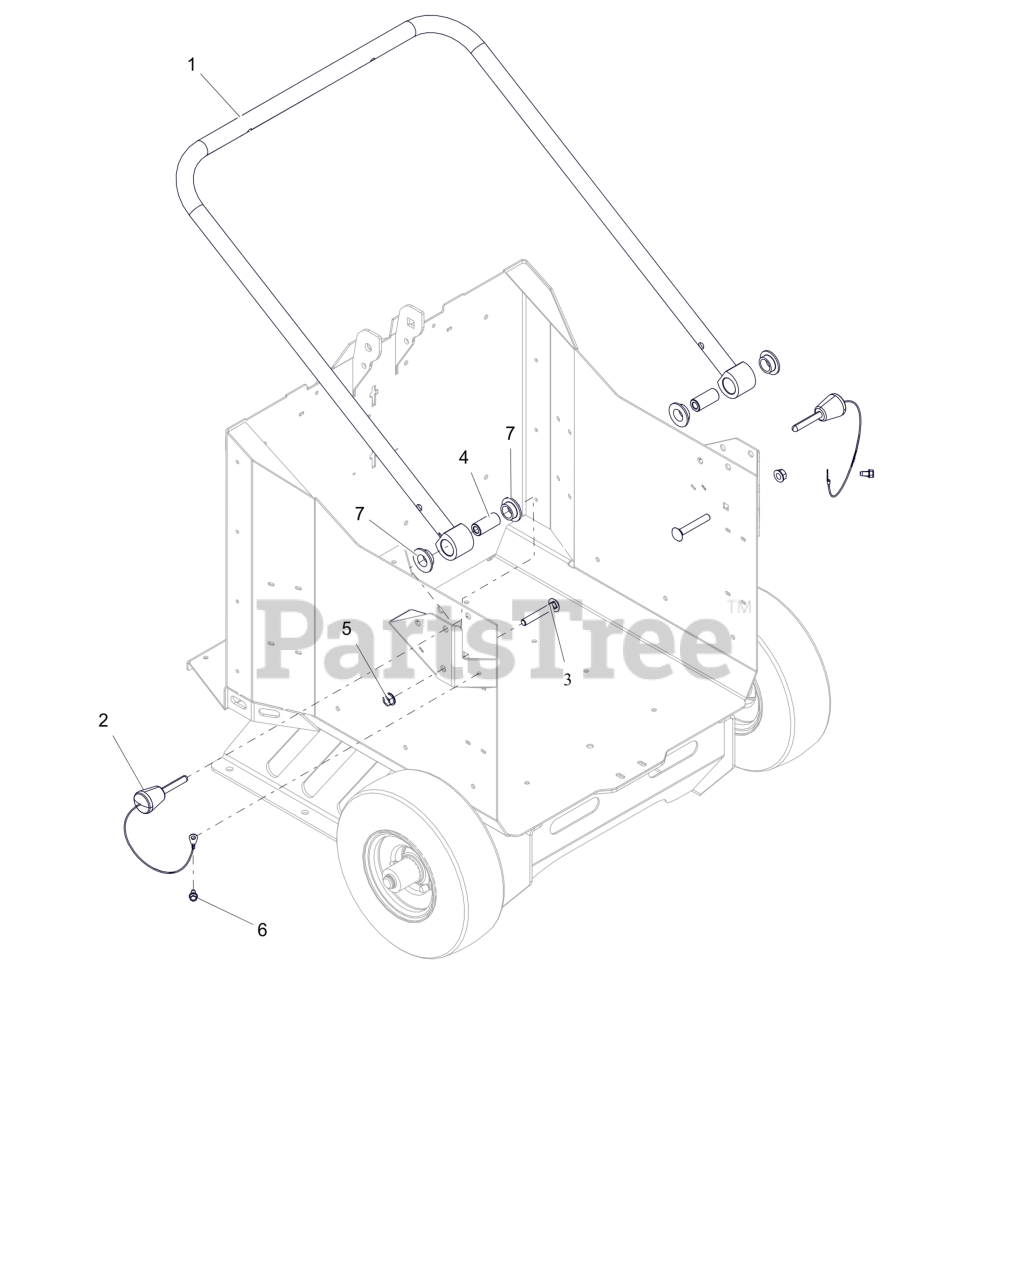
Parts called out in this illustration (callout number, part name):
1	WLDMT, HANDLE (BLUE)
2	PIN, MAGNETIC .375X2.188
3	BLT,RHSN .38-16X2.50 G5 ZCC
4	SPACER, STEERING ARM
5	NUT-LK-TOP-FLG .375-16 GG ZCC
6	SCR-TAP .25-20X.50 HWH ZCC
7	BSHG-FLG .762X1.48X.44 NYL
